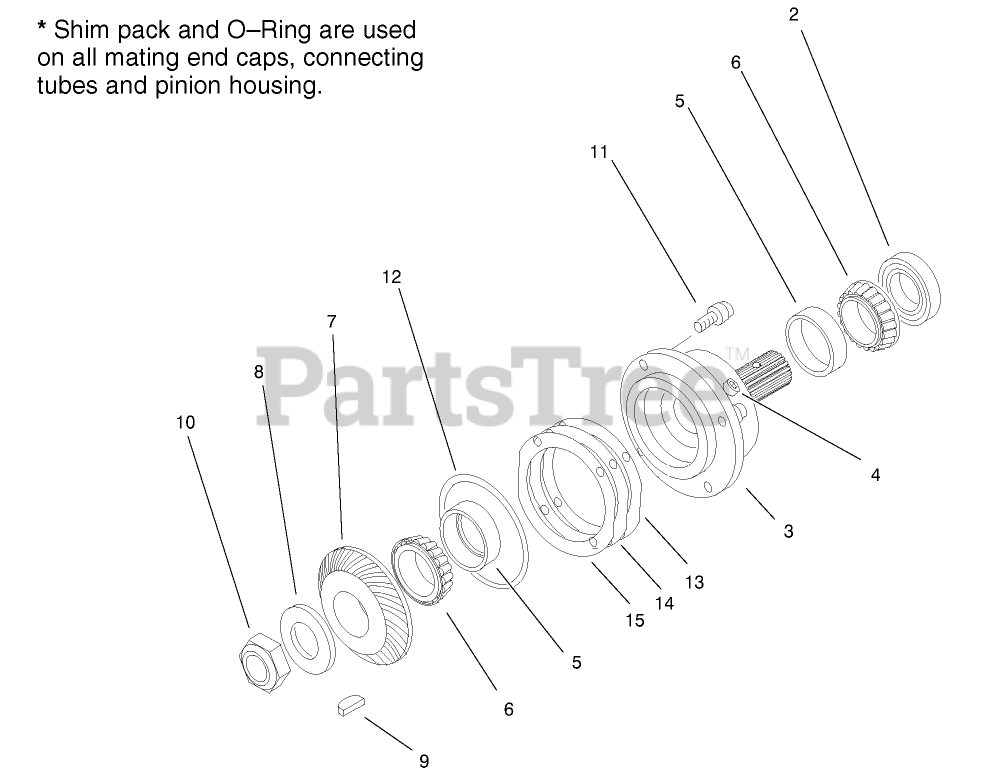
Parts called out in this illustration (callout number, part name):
3	HOUSING - PINION
5	Bearing-Cup
6	Bearing-Cone
7	GEAR - 27 TOOTH
8	WASHER
9	KEY-WOODRUFF
10	NUT-JAM
12	O-RING
13	SHIM-BROWN, .010IN
14	SHIM-BLUE, .005IN
15	SHIM-GREEN, .003IN
